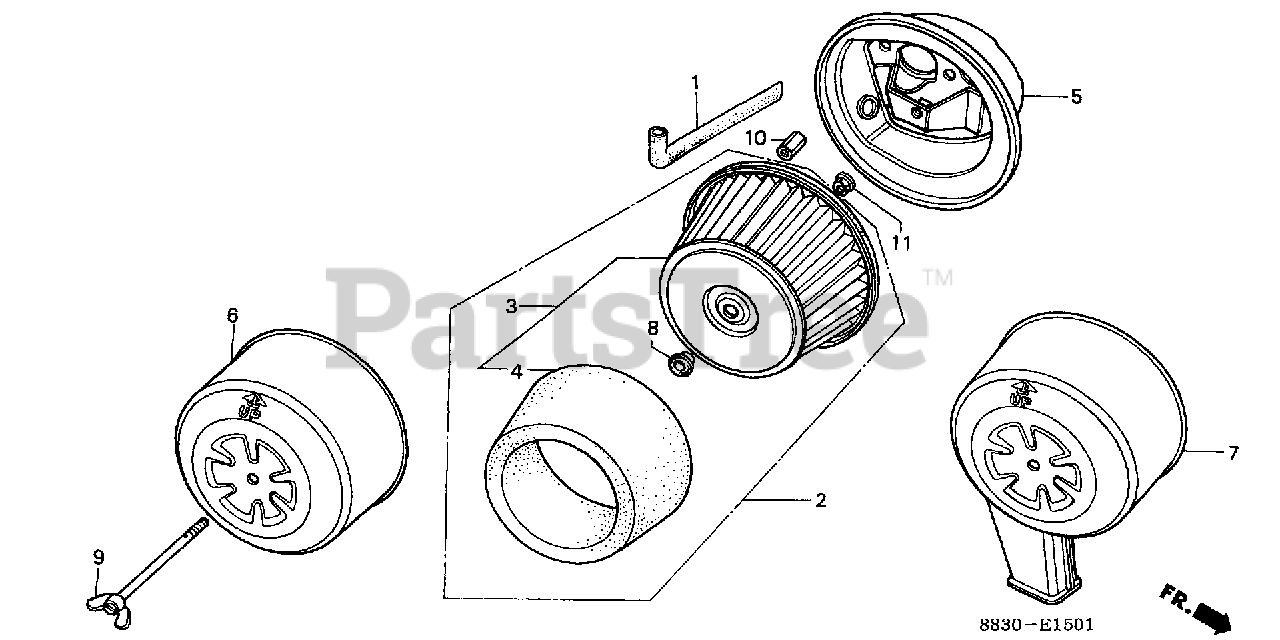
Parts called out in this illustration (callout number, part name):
2	ELEMENT, AIR CLEANER Use from Engine SN 1541113 to 2342662.
3	ELEMENT, AIR CLEANER Use from Engine SN 2342663.
4	ELEMENT B, AIR CLEANER Use from Engine SN 1541113.
